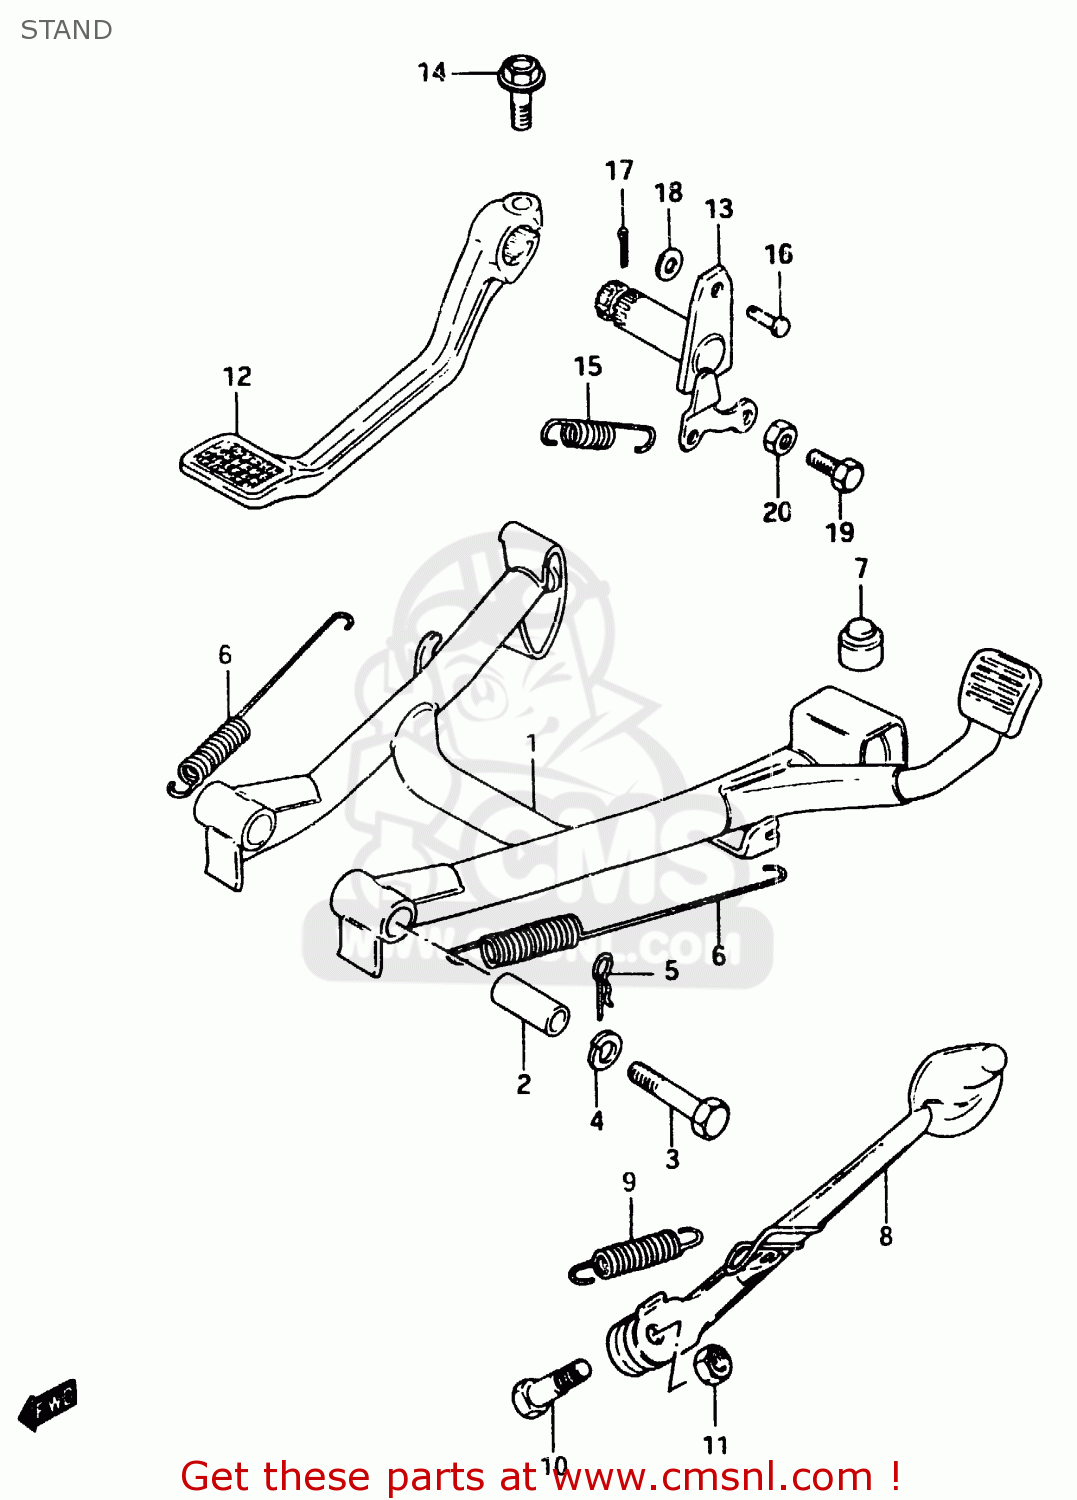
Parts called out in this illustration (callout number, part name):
1	STAND,CENTER
2	SPACER(10X16X38.8)
3	BOLT
4	LOCK WASHER
5	CLIP
6	SPRING
7	CUSHION
8	STAND,SIDE
9	SPRING
10	BOLT(10X32)
11	NUTM10X1.25X8
12	PEDAL,BRAKE
13	ARM,BRAKE PEDAL
14	BOLT
15	SPRING
16	PIN
17	PIN
18	WASHER
19	BOLT
20	NUT
